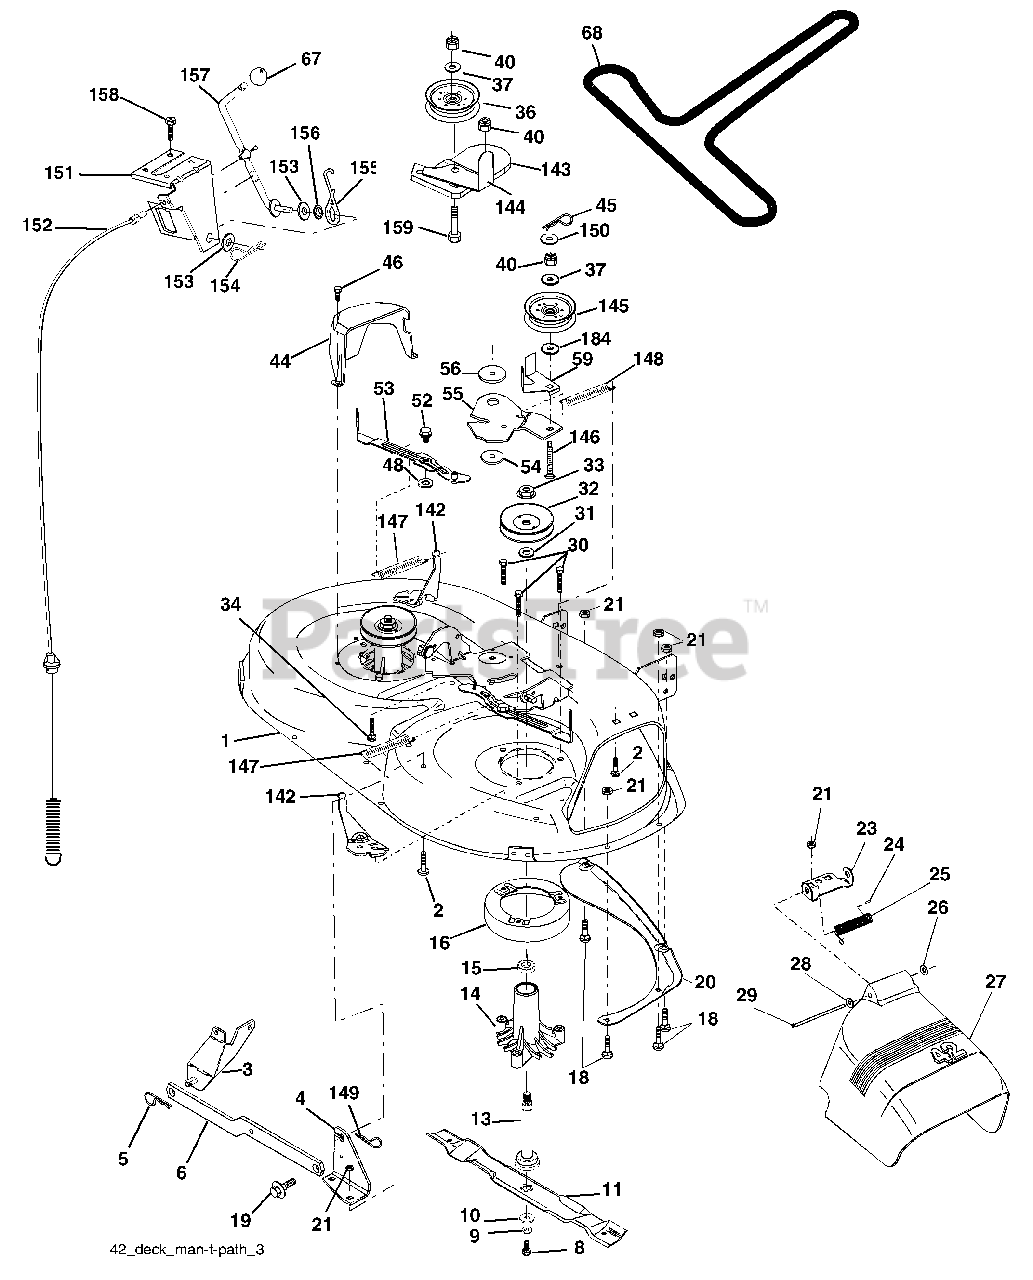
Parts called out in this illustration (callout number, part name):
1	Mower Deck Assembly, 42"
2	Bolt
3	Bracket Asm Fr. Sway Bar 3/42
4	Bracket Asm Deck 42" Sway Bar
5	Retainer Spring
6	Bar Sway Deck
8	Bolt 3/8-24 x 25 Grade 8 patched
9	Washer, Lock
10	Washer, Hardened
11	Blade, 42" Mulching Std
11	Blade, 42" Mulching Premium
11	Blade, 42" Hi-Lift
13	Shaft Assembly, Mandrel, Vented
14	Housing, Mandrel, Vented
15	Bearing, Ball, Mandrel
16	Stripper, Mandrel Deck
18	Bolt, Carriage 5/16-18 x 5/8
19	Bolt, Shoulder
20	Baffle, Vortex
21	Nut
23	Bracket, Deflector Mower 42"
24	Cap, Sleeve 80 x 112 Blk Mower
25	Spring, Torsion, Deflector 2 52
26	Nut, Push Phos & Oil
27	Shield, Deflector 42" Blk
28	Washer 11/32 x 5/8 x 16 Gauge
29	Rod, Hinge 42" 6 75 W/G
30	Screw Thdrol Washer Head
31	Washer, Spacer Mower Vented
32	Pulley, Mandrel
33	Nut, Toplock 9/16 Flange
34	Bolt
36	Pulley, Idler, Flat
37	Washer 13/32 x 13/16 x 16 Gauge
40	Nut
44	Guard, Mandrel, LH
45	Retainer
46	Screw, Thdrol 1/4-20 x 5/8 T
48	Washer, Hardened
52	Bolt, Shoulder 5/16-18 Unc
53	Arm Assembly, Pad, Brake
54	Washer, Hardened
55	Arm, Idler
56	Spacer, Retainer
59	Guard TUV Idler
67	Knob
68	V-Belt, 42" Mower
142	Arm Spring Brake Mower
143	Bracket Arm Idler 42"
144	Keeper Belt 42" Clutch Cable
145	Pulley Idler Flat
146	Bolt Carriage Idler
147	Spring Extension
148	Spring Return Idler
149	Retainer Spring Yellow
150	Washer 9/32 x 3/4 x 16 Ga.
151	Bracket Clutch Cable
152	Clutch Cable 42"
153	Washer Flat 3/8" Type B
154	Spring Retainer
155	Spring Retention LVR CLTCH CAB
156	Spacer Clutch Cable
157	Rod Clutch Cable 3/8"
158	Screw Hex Thd Cut 1/4-20 x 1/2
159	Bolt Rdhd Sqn 3/8-16 Unc x 1-3/4
184	Washer 13/32 x 7/8 x 10 Ga.
